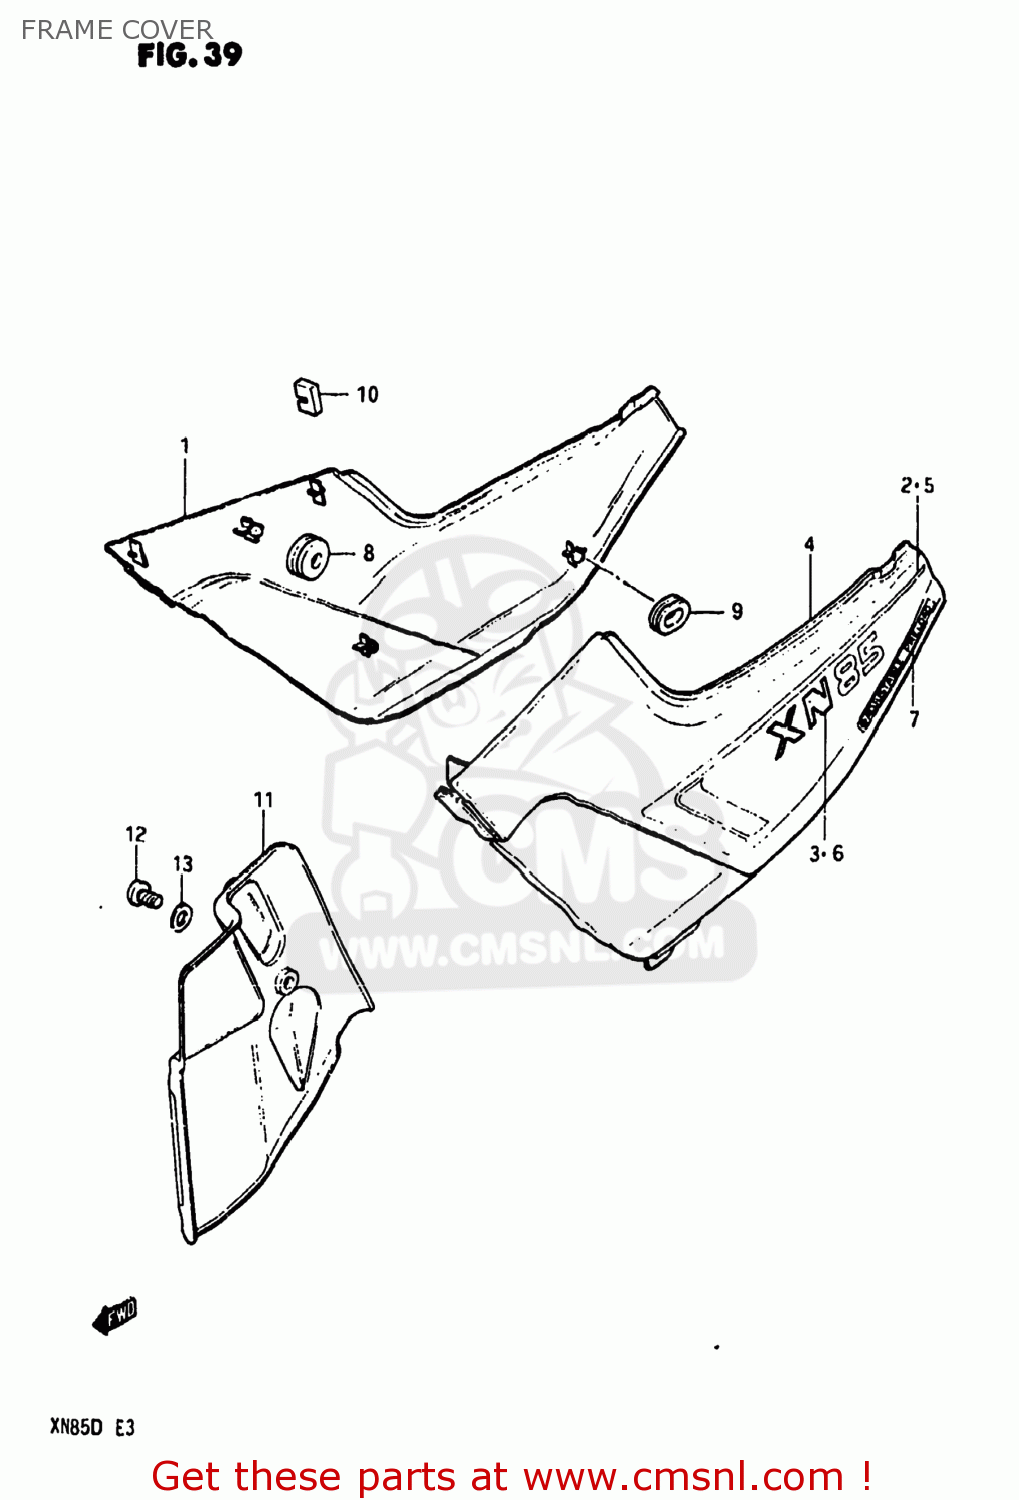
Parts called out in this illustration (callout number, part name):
1	COVER,FRAME,RIGHT
2	TAPE SET,FRAME COVER
3	EMBLEM (XN85)
4	COVER,FRAME,LEFT
5	TAPE SET,FRAME COVER
6	EMBLEM (XN85)
7	EMBLEM
8	CUSHION
9	CUSHION
10	CUSHION
11	COVER,FUEL PUMP
12	SCREW 6X12
13	WASHER
